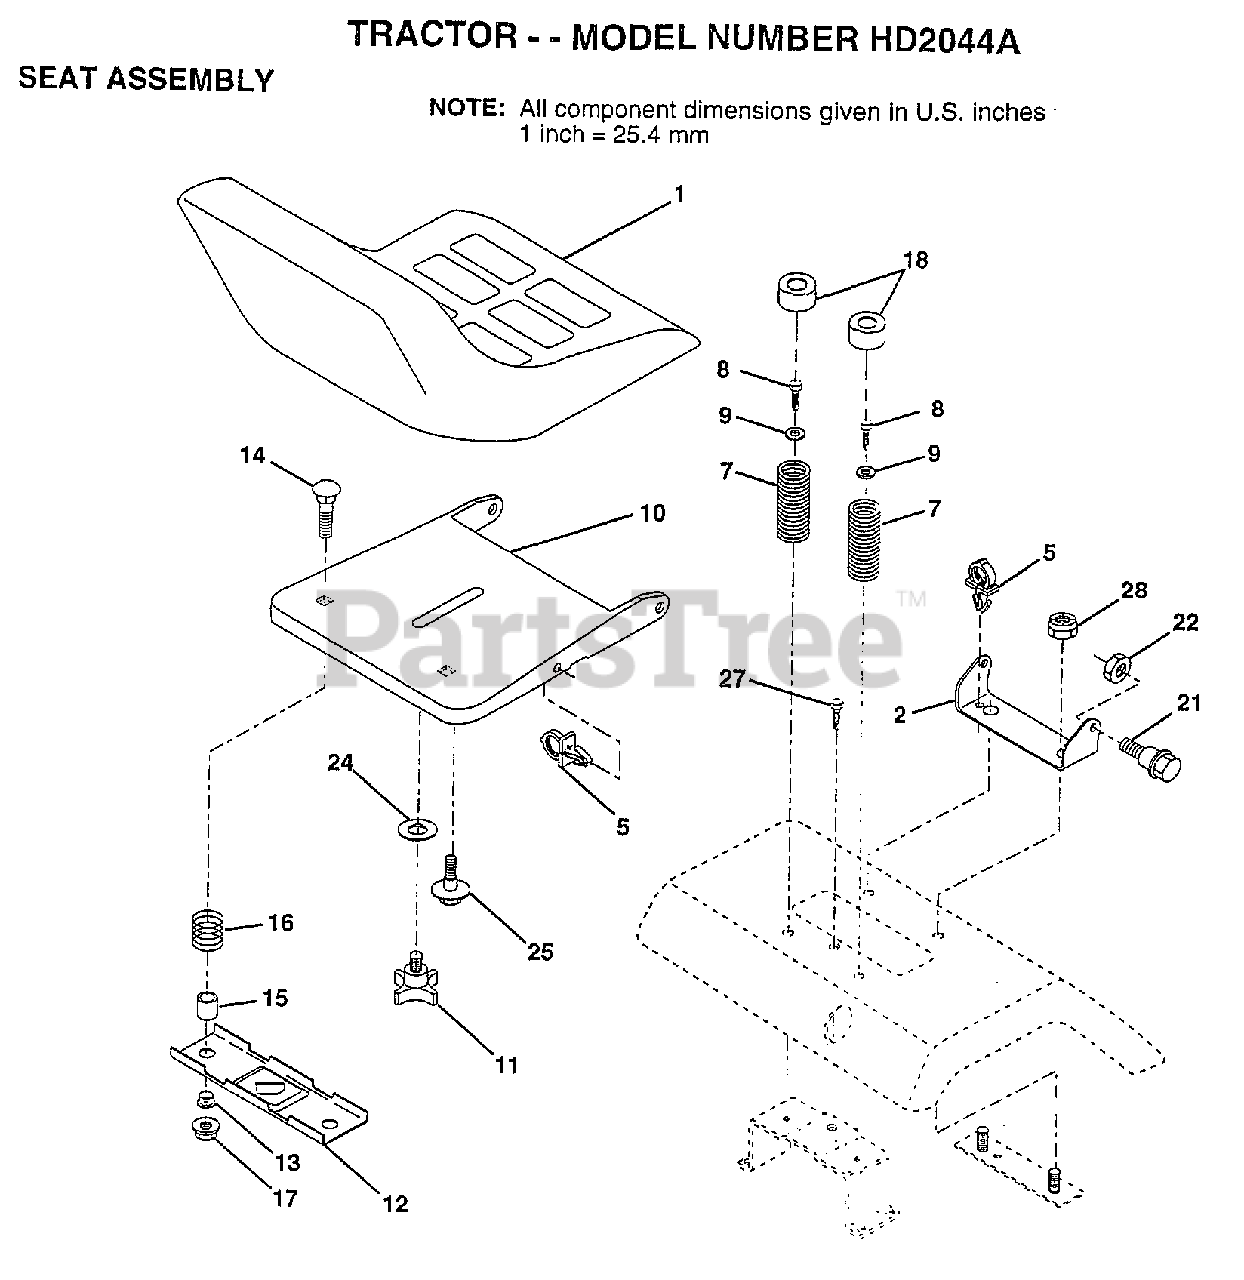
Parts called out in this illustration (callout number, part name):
1	SEAT.2500/1516.BK
2	BRACKET PVT SEAT
5	CLIP.PUSH-IN.HING
7	SPRING COMPRESSIO
9	WASHER
11	"KNOB 1/2"" YT"
12	BRKT SWITCH
13	BUSHING
15	SPACER SPLIT
16	SPRING COMPRESSED
18	CAP SPRING
21	BOLT.SHLD.5/16-18
24	WASHER
25	"BOLT,SHOULDER"
27	SCREW LT
